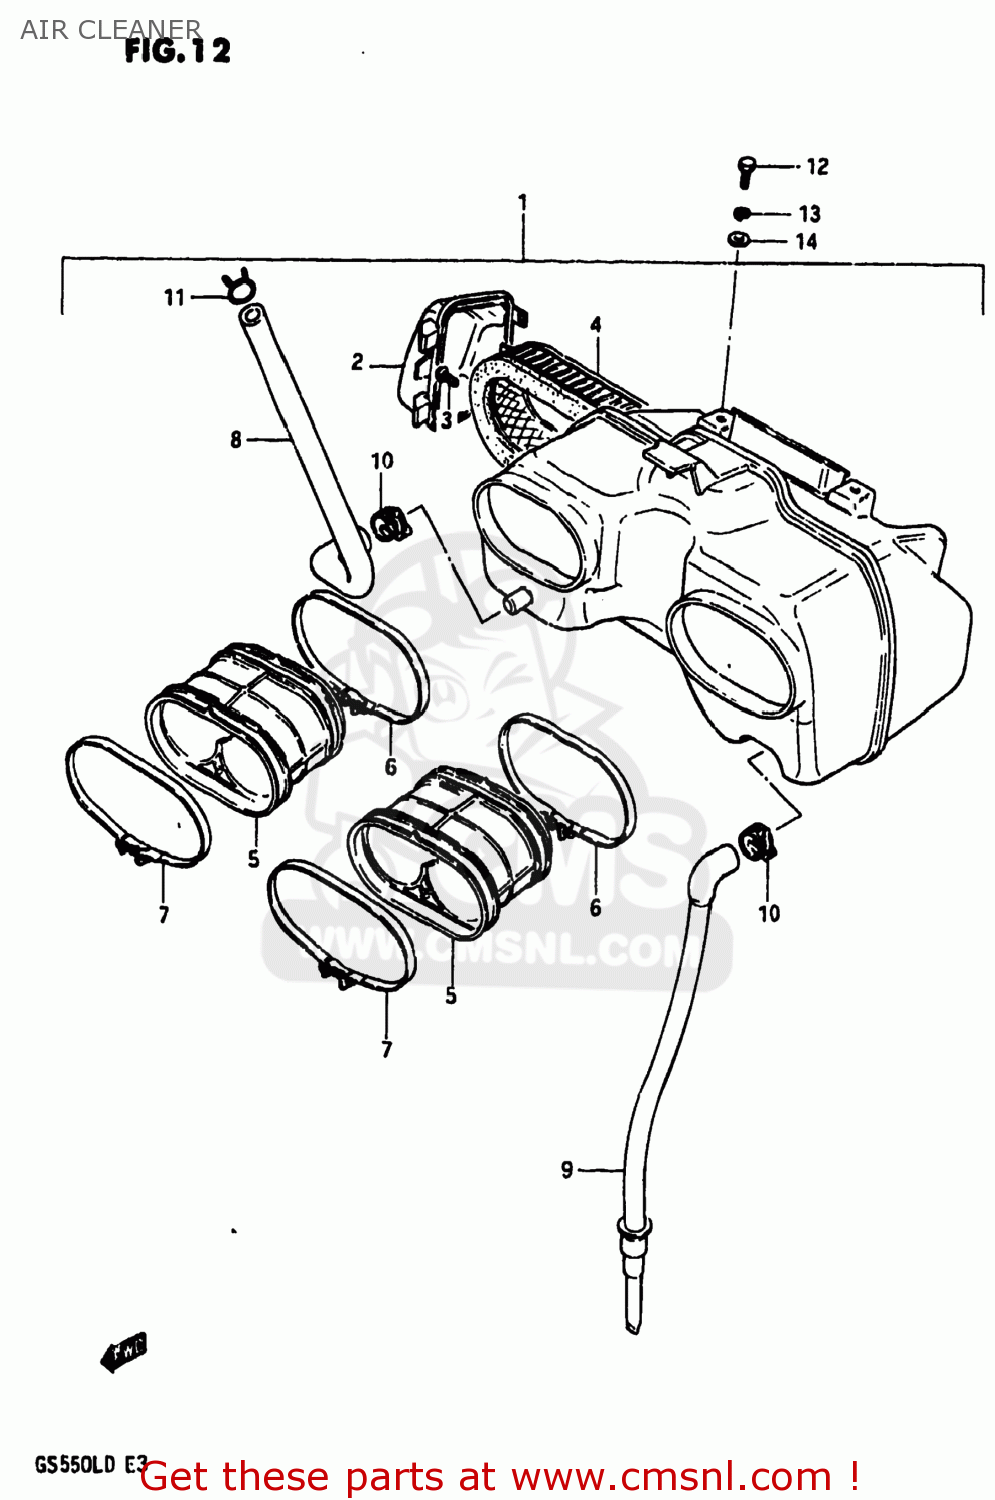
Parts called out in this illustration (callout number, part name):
1	CLEANER ASSEMBLY,AIR
2	CAP,AIR CLEANER
3	SCREW M5X12 DIN 7985/N
4	FILTER,AIR CLEANER
5	TUBE,AIR CLEANER OUTLET
6	CLAMP
7	CLAMP
8	TUBE,BREATHER
9	DRAIN TUBE
10	CLIP
11	CLIP,BREATHER TUBE
12	BOLT, UPPER
13	LOCK WASHER
14	WASHER
